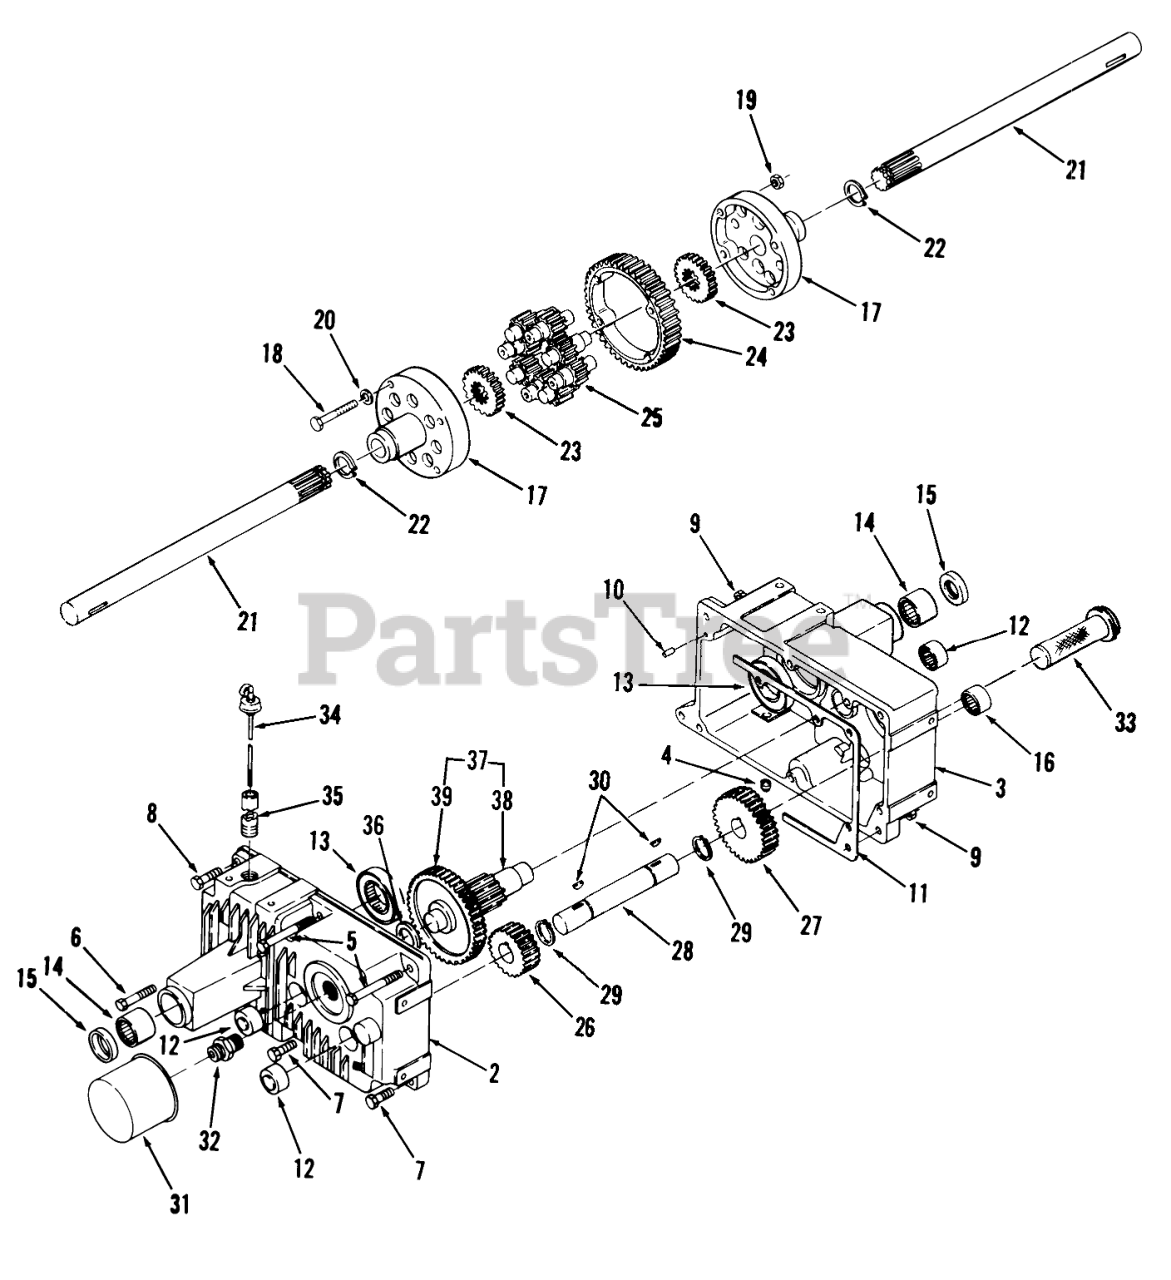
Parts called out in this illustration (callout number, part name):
1	Transaxle Complete
2	Case RH
3	CASE-AUTOMATIC LH
4	PLUG 1/4 PIPE ALLEN
5	H H C S
6	HHCS
7	Bolt
8	Bolt
9	Nut
10	PIN-DOWEL
11	GASKET
12	BEARING-NEEDLE
13	BALL BRG 1 1/2 I.D.
14	BEARING
15	SEAL-OIL
16	Needle Bearing
17	DIFFERENTIAL END CAP
18	BOLT-HEX
19	Nut
20	WASHER
21	AXLE-REAR
22	RING-SNAP
23	GEAR-AXLE DIFFERENTIAL
24	GEAR-DIFFERENTIAL RING, 43T
25	GEAR-PINION, 11T
26	GEAR 24T
27	Gear 44T
28	SHAFT GEAR
29	Snap Ring
30	Key
31	Filter
32	FITTING
33	STRAINER
34	ASSY-DIPSTICK
35	NIPPLE-TRANS FILL
36	WASHER-THRUST
37	GEAR ASSY
38	PINION SHAFT
39	Gear-42T
